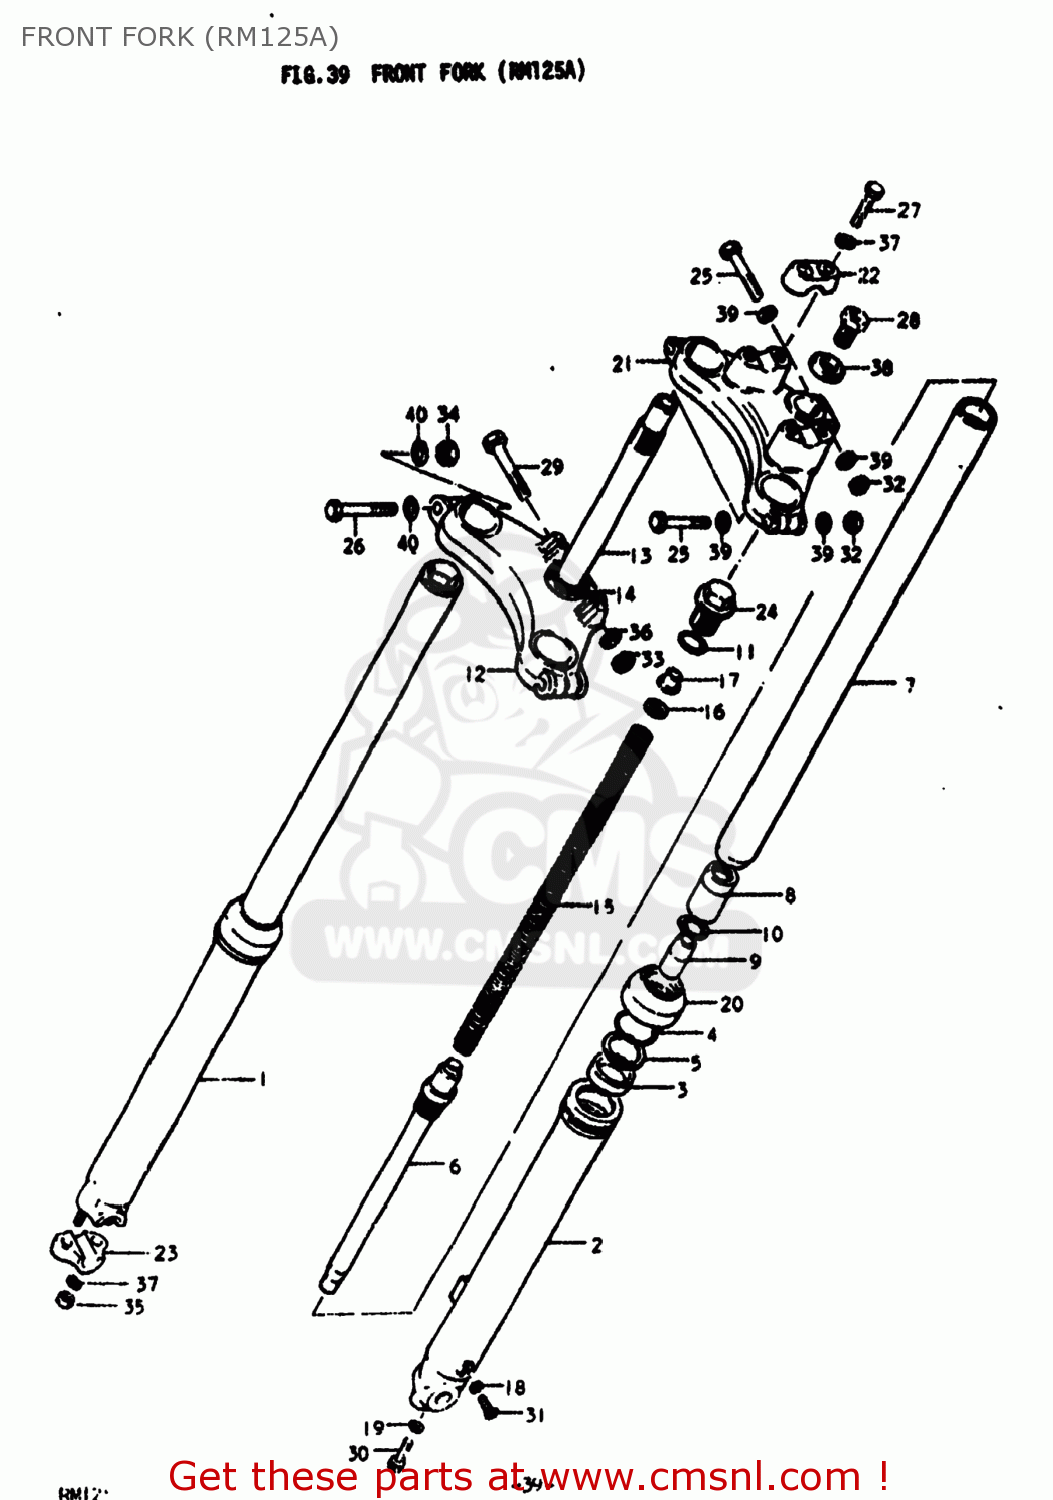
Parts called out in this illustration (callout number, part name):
0	DAMPER SET
1	TUBE,OUTER,RIGHT
2	TUBE,OUTER,LEFT
3	SEAL,OIL
4	CIRCLIP,FORK OIL SEAL
5	RING,FORK BACK UP
6	CYLINDER,FRONT FORK
7	TUBE,FORK,INNER
8	PISTON,FORK INNER TUBE
9	PIECE,OIL LOCK
10	RING
11	O RING
12	STEM,STEERING
13	STEM,STEERING
14	RACE,STEERING OUTER LWR
15	SPRING
16	WASHER,STEERING STEM HEAD
17	SPACER,SPRING
18	GASKET,DRAIN,PLUG (NAS)
19	GASKET (NAS)
20	SEAL,DUST
21	HEAD,STEERING STEM
22	HOLDER,HANDLEBAR
23	HOLDER,AXLE
24	BOLT,FORK
25	Bolt 8X50
26	BOLT
27	Bolt
28	BOLT,STEERING STEM HEAD
29	BOLT
30	BOLT
31	SCREW
32	NUT
33	NUT
34	NUT
35	NUT (8MM)
36	LOCK WASHER
37	LOCK WASHER
38	WASHER
39	WASHER
40	WASHER
